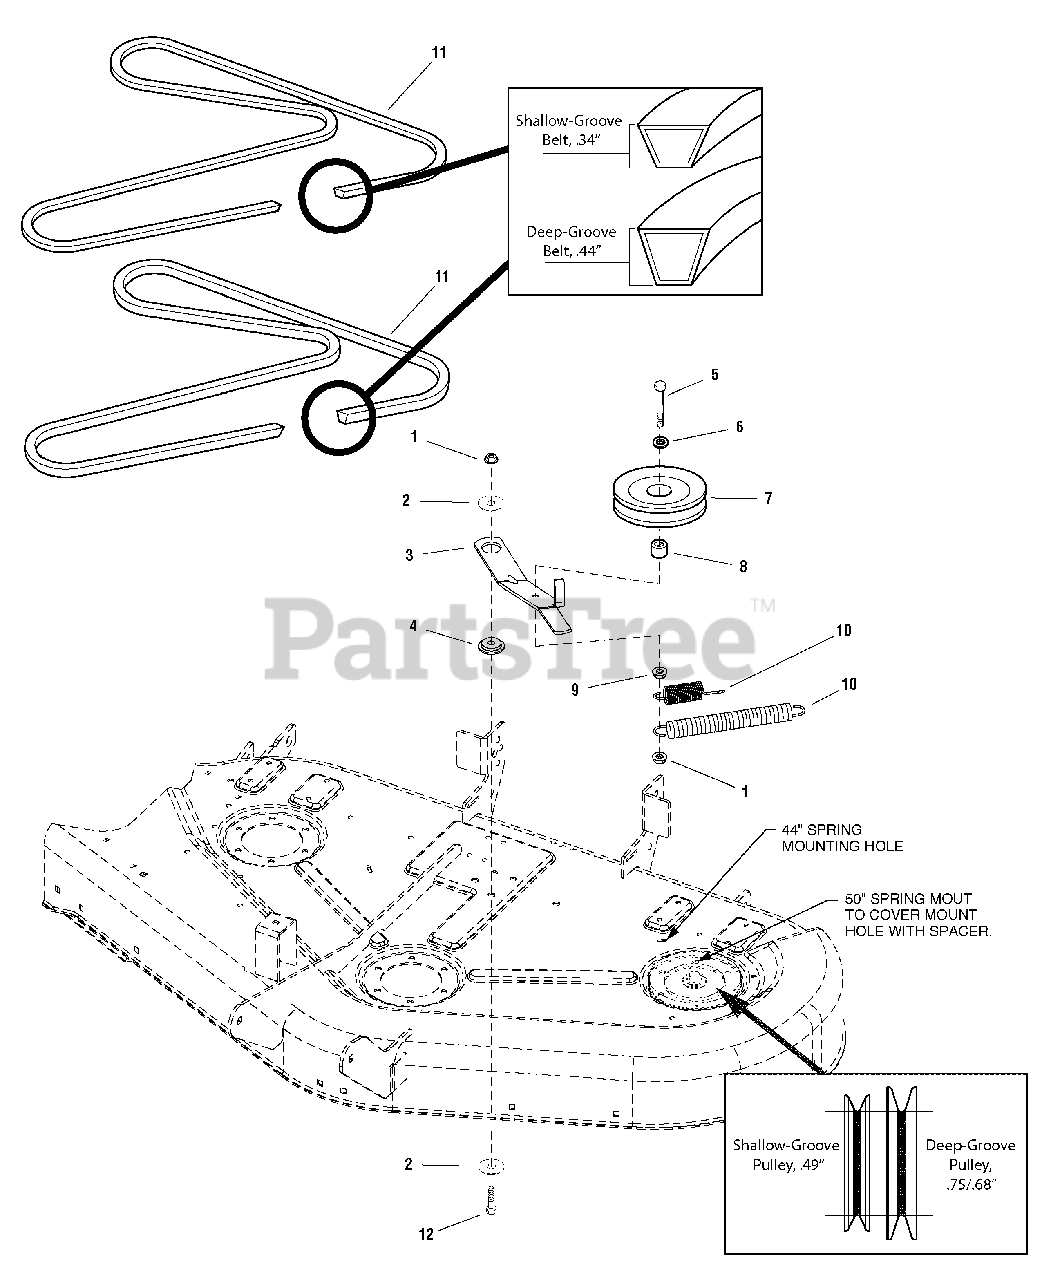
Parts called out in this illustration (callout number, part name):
1	NUT, Hex Flange Center Locking, 3/8-16
2	WASHER, Plain, 13/32 x 1-1/2 x 1/8
3	ARM, Idler 7GA
4	SPACER
5	CAPSCREW, Hex Head, 3/8-16 x 2-1/2
6	WASHER, 3/8
7	PULLEY ASSEMBLY
8	SPACER
9	NUT, Whizlock, 3/8-16
10	SPRING, Extension, Idler Arm
11	V-BELT, Arbor Drive, Deep-Groove, 44" Deck
11	V-BELT, Arbor Drive, .34" Shallow-Groove, 44" Deck
11	V-BELT, Arbor Drive, .44" Deep-Groove, A-Wedge, 50" Deck
11	V-BELT, Arbor Drive, .34" Shallow-Groove, 50" Deck
11	V-BELT, Arbor Drive, .44" Deep-Groove, 44" Deck
12	CAPSCREW, Hex Head, 3/8-16 x 1-1/4, G8
